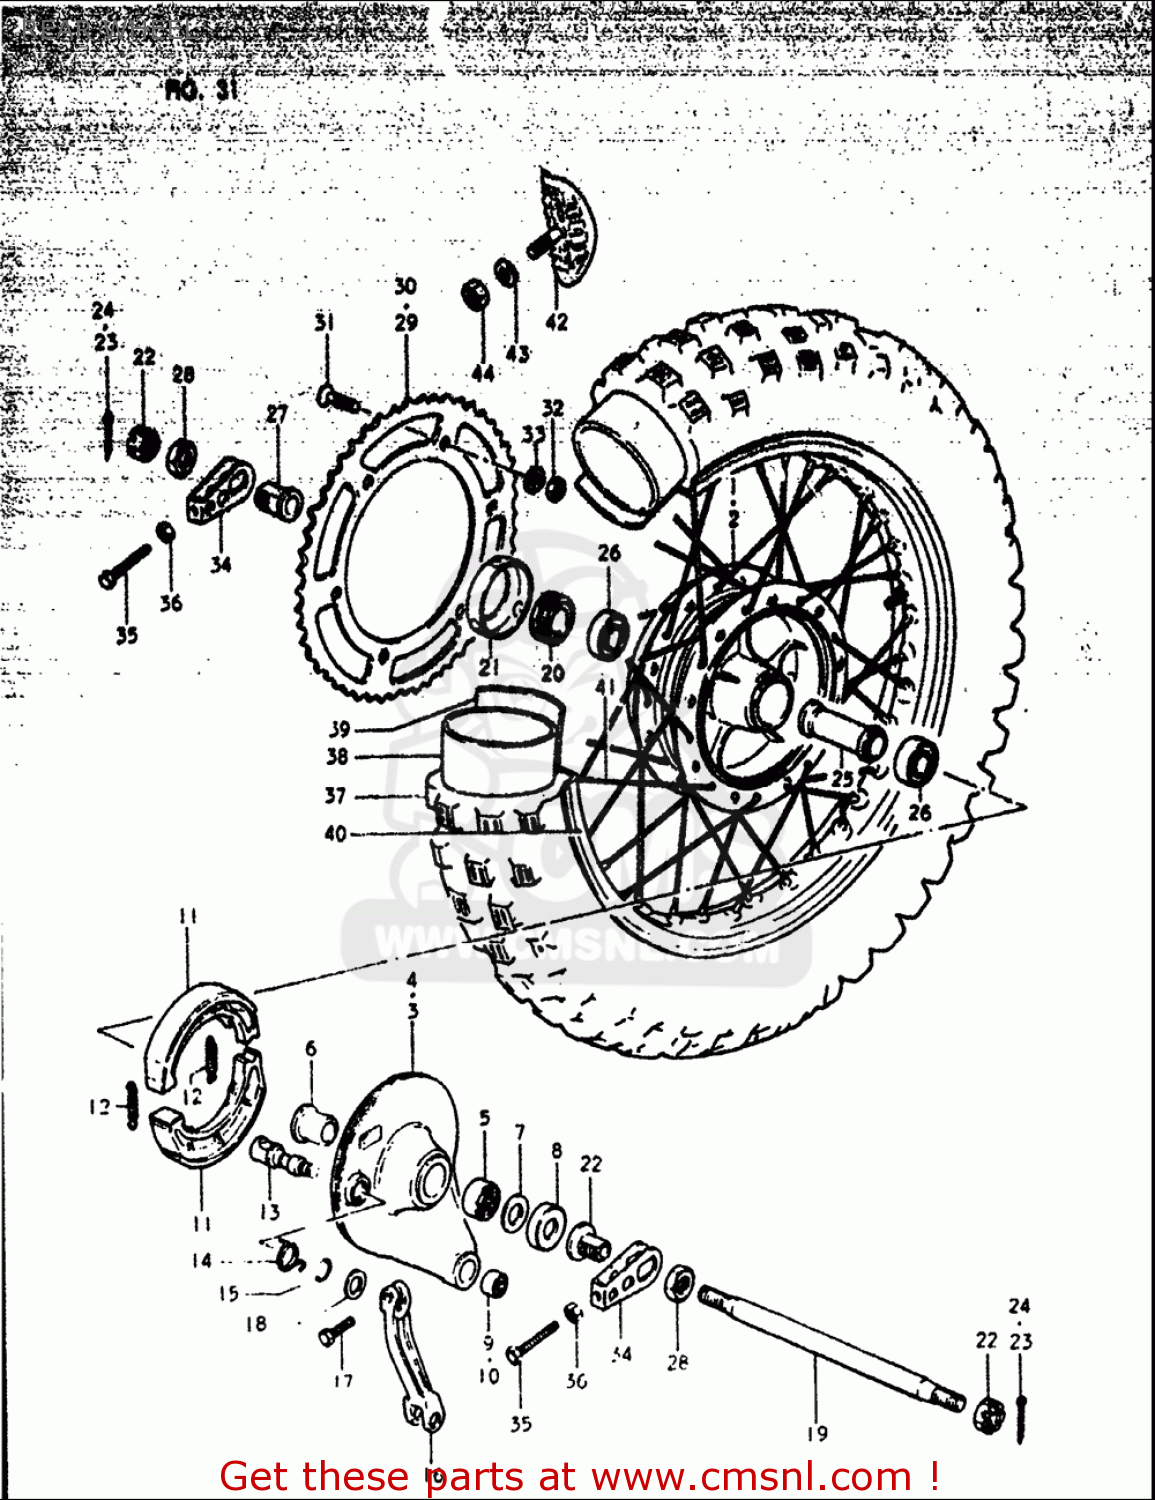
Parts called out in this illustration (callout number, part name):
5	BEARING(22X29X25)
6	SPACER,REAR HUB PANEL
7	WASHER (15X30X2.0)
8	SEAL,RR SWGARM PIVOT DUST
9	BUSH
10	SPHERICAL BRNG,TORQUE LINK
11	SHOE SET,BRAKE (MCA)
12	SPRING(L:35.8)
13	CAM,FR BRAKE
15	O RING(D:2.5,ID:11.4)
16	LEVER,RR BRAKE CAM
17	BOLT
18	WASHER(12.5X20X1)
22	NUT
23	PIN 30X40
24	PIN
26	BEARING
28	NUT
30	SPROCKET,RR(NT:50)
31	SCREW(8X33.5)
32	NUT
33	WASHER
34	ADJUSTER,CHAIN
35	BOLT(8X50)
36	NUT
38	TUBE ASSEMBLY,WHEEL,INNER
39	PROTECTOR,INNER TUBE
41	SPOKE SET,REAR
42	STOPPER,BEAD(1.85)
43	WASHER
44	NUT
